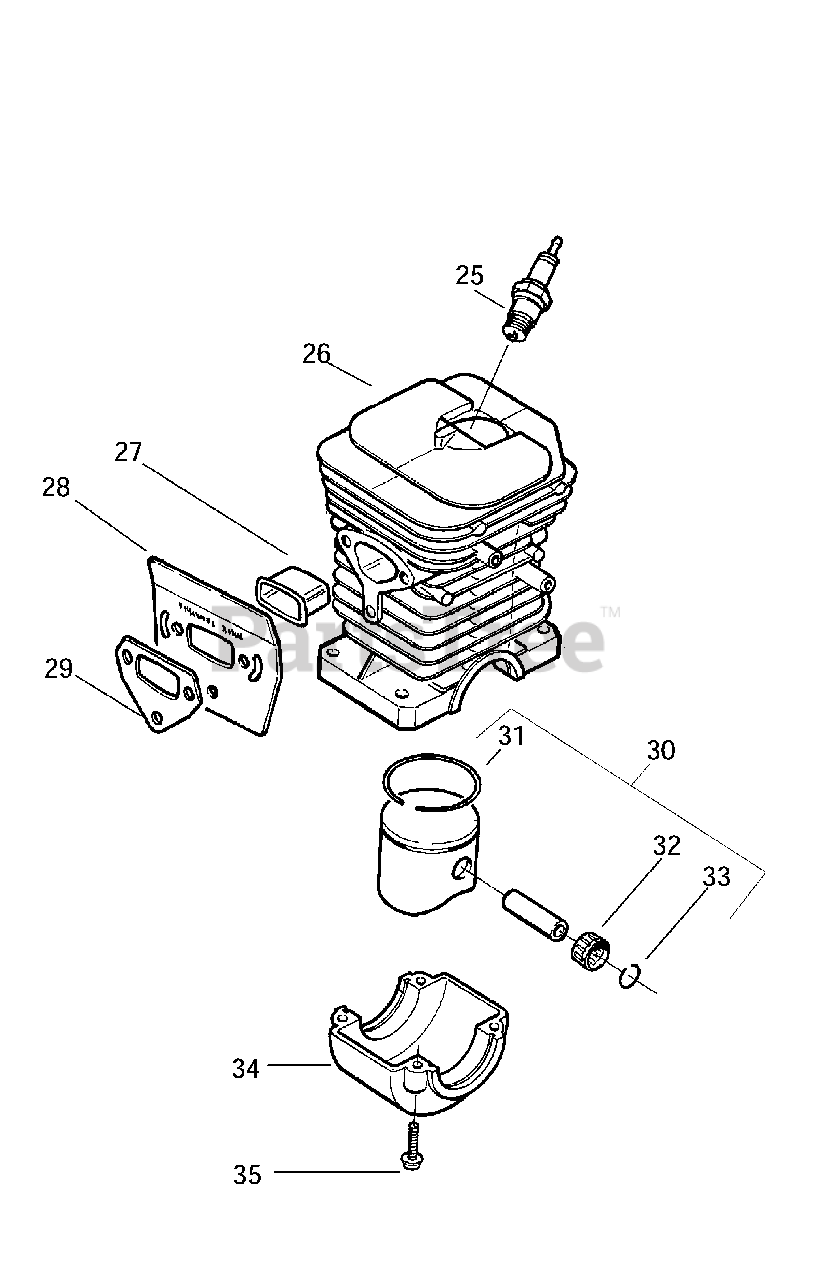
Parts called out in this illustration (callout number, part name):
25	Spark Plug (RCJ-7Y)
26	Kit-Cylinder (136)
26	Kit-Cylinder (141)
27	Heat Insulator
28	Muffler-Plate
29	Muffler Gasket
30	Piston Kit (136)
30	Piston Kit (141)
31	Piston Ring (136)
31	Piston Ring (141)
32	Piston Pin Bearing
33	Piston Pin Retainer
34	Cap-Crankcase
